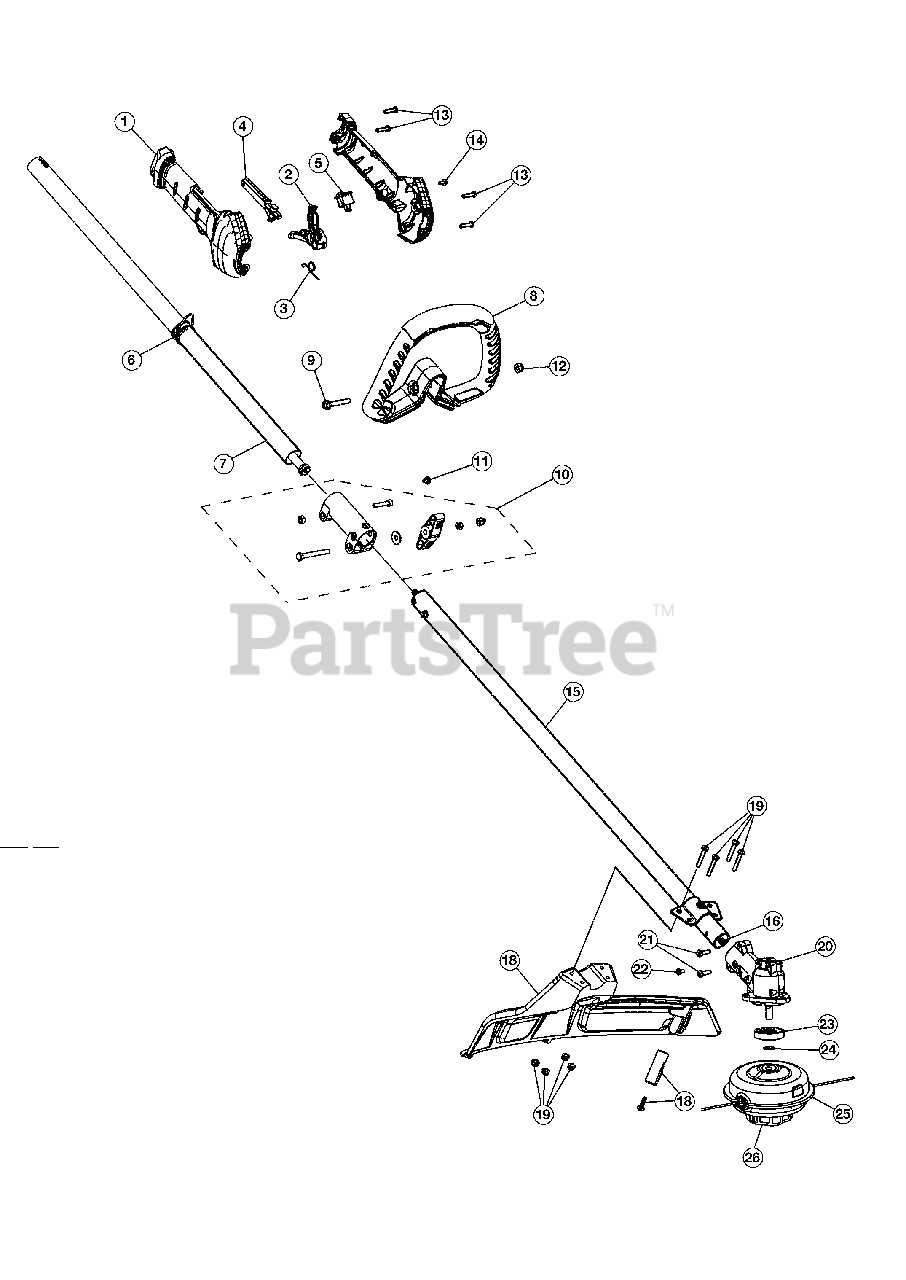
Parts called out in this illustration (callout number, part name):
1	Grip Assembly (Incl. 2 - 5, 13 and 14)
2	Throttle Trigger
4	Throttle Lockout
6	Shoulder Strap Clip
7	Upper Drive Shaft Housing
8	Handle Assembly (Incl. 9 and 12)
10	Split Boom Coupler (Incl. 11)
11	Coupler Anti-Rotation Screw
14	Grip Anti-Rotation Screw
15	Lower Drive Shaft Housing Assembly (Incl. 16)
16	Lower Flexible Drive Shaft
18	Shield Assembly (Includes Blade)
18	Blade Assembly
19	Shield Mounting Screw and Nut
20	Gearbox (Incl. 21 - 25)
21	Gearbox Mounting Hardware
22	Anti-Rotation Screw
23	Cutting Head Driver
25	Cutting Head Assembly
